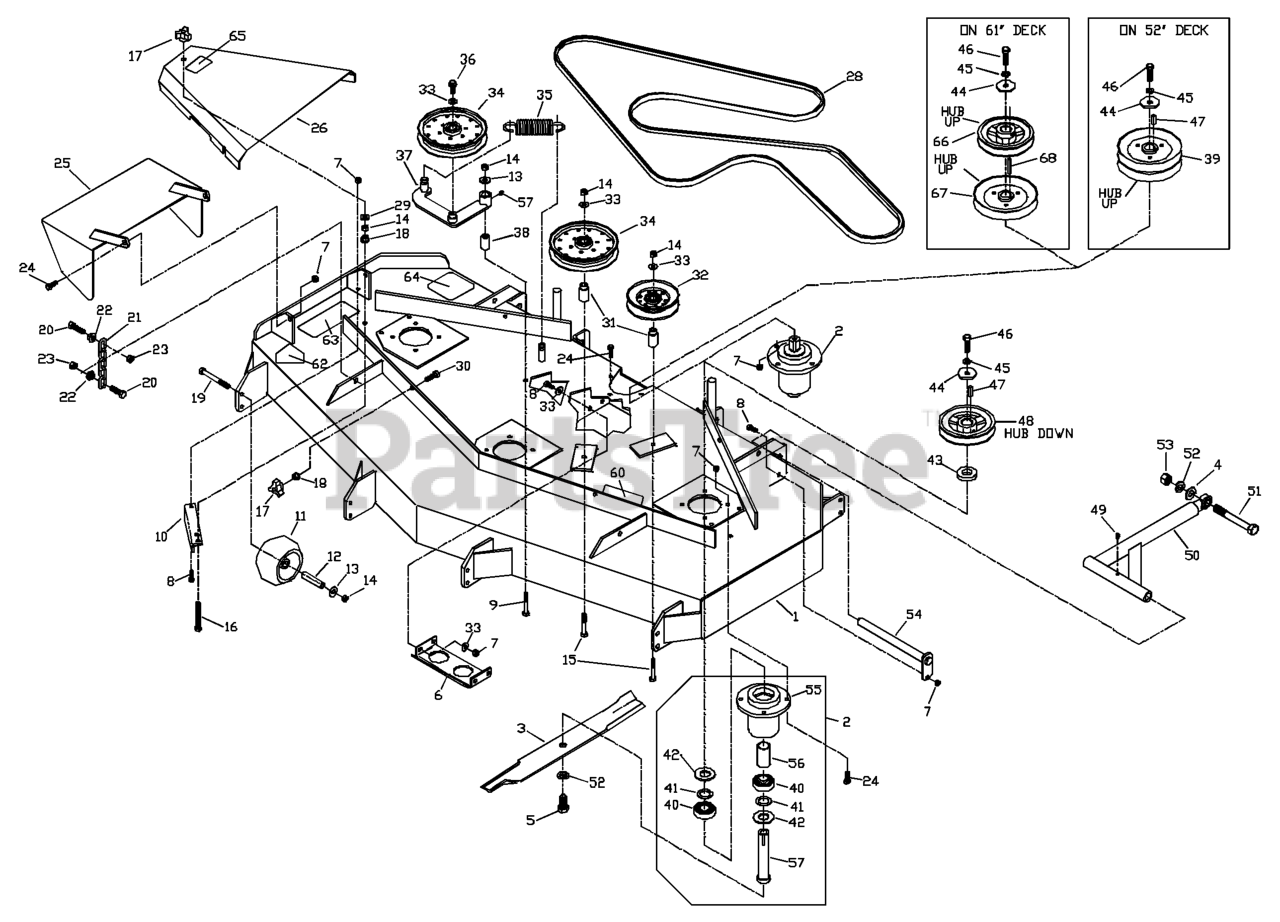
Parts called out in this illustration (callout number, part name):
1	DECK FRONT W/DECALS 61"
1	FRONT DECK, 52" W/DECALS
2	HOUSING ASSEMBLY
3	BLADE OEM 21" (61" DECK)
3	BLADE OEM 18"
4	WASHER 5/8 FLAT
5	HCS 5/8F X 1 1/4
6	DNB GUARD,PAINTED-BLACK
7	NUT 5/16C CENTERLOCK
8	HCS 5/16C X 3/4
9	HCS 3/8C X 3
11	ANTI-SCALP ROLLER
13	WASHER 3/8 FLAT
14	NUT 3/8C CENTERBLOCK
15	SCREW 3/8C X 2 3/4 HEX CAP
16	TAP BOLT 3/8C X 4
17	KNOB, THREE PRONG
18	NUT 3/8C WHIZ
19	HCS 3/8C X 3 1/2
20	HCS 7/16C X 1 1/2
21	LIFT CHAIN
22	NUT 7/16C WHIZ
23	NUT 7/16C CENTERLOCK
24	HCS 5/16C X 1
25	DISCHARGE CHUTE
26	BELT SHIELD (61" DECK)
26	BELT SHIELD (52" DECK_
28	BELT, BLADE (61" DECK)
28	BELT, BLADE 52"DECK
29	WASHER, 3/8 SEALING
30	HCS 3/8C X 1 1/4 GR5
31	IDLER BUSHING
32	IDLER PULLEY
33	WASHER 5/16 FLAT
34	IDLER PULLEY
36	4CS 3/8C X 1 SERRATED HEAD
38	SLEEVE BUSHING
39	PULLEY, DOUBLE 52"
40	BEARING
41	BUSHING.MACHINE.18.GAUGE
42	MACHINERY BUSHING 10 GA.
44	WASHER, CRANKSHAFT
45	WASHER 7/16 LOCK
46	HCS 7/16F X 1 1/2
47	KEY 1/4 SQ X 1 1/8
48	PULLEY, ENGINE
48	PULLEY
49	ZERK
50	STRUT, LEFT
51	SCREW 5/8C X 5 HEX CAP
52	LOCKWASHER 5/8
53	NUT 5/8C HEX
57	SPINDLE SHAFT
60	DECAL, BELT ROUTING
62	DECAL, CPSC
63	DECAL, DANGER
64	DECAL, ANTI-SCALP
65	DECAL, NO STEP
66	PULLEY
67	PULLEY (61" JACK SHAFT)
68	KEY 1/4" SQ X 1 7/8"
